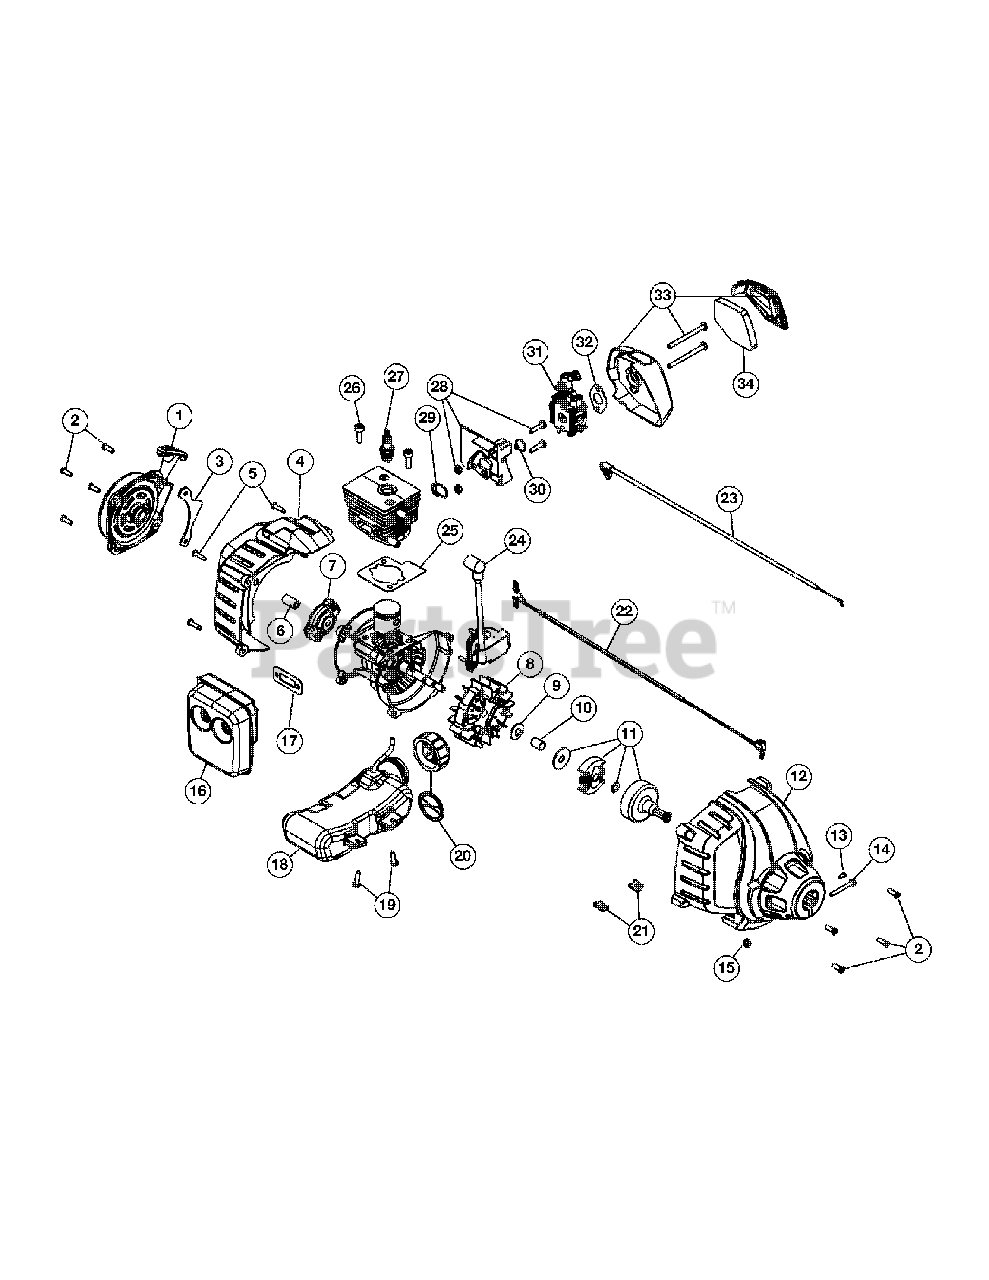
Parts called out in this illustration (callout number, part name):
1	Rear Cover Assembly
2	Starter Screw
3	Starter Assembly Guard
4	Rear Engine Cover
5	Cover Screw
7	Pawl Assembly
8	Flywheel Assembly
11	Clutch Assembly
12	Clutch Cover Assembly
13	Anti Rotation Screw
14	Clamp Screw
15	Clamp Nut
16	Muffler Assembly
17	Muffler Gasket
18	Fuel Tank Assembly
21	U-Shaped Nut
22	Lead Wires
23	Throttle Cables
24	Module Assembly
25	Cylinder Gasket
26	Cylinder Bolt
27	Spark Plug
28	Insulator Assembly
29	Insulator O-Ring
30	Carburetor O-Ring
31	Carburetor
32	Carburetor Gasket
33	Aircleaner Assembly
34	Aircleaner Filter
